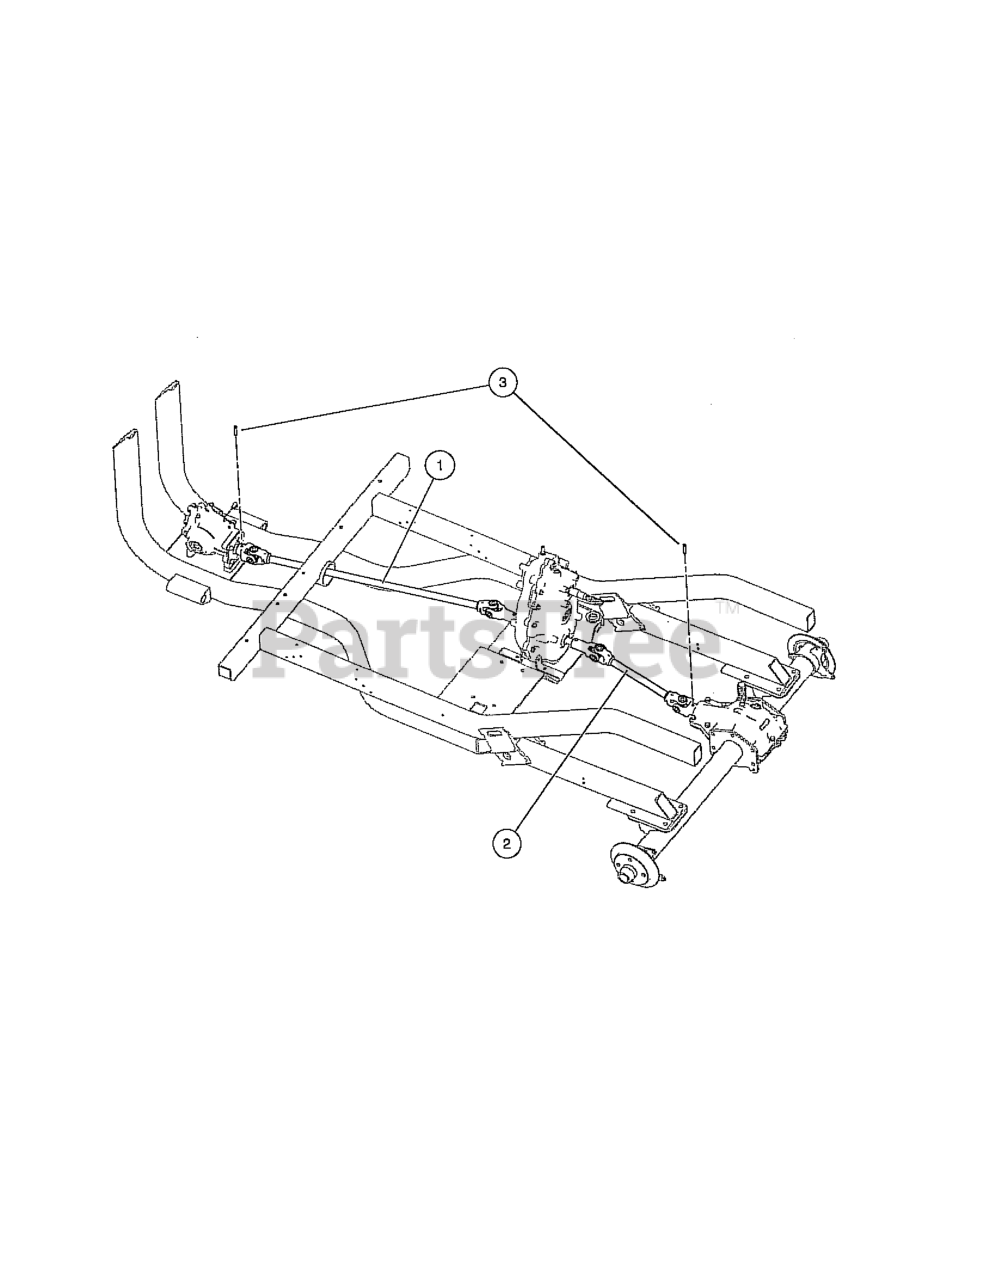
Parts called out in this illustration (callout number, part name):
1	PROP SHAFT, FRONT
2	PROP SHAFT, REAR - 105173301
3	PIN, SPRING, 5/16 X 1-1/2 HD
